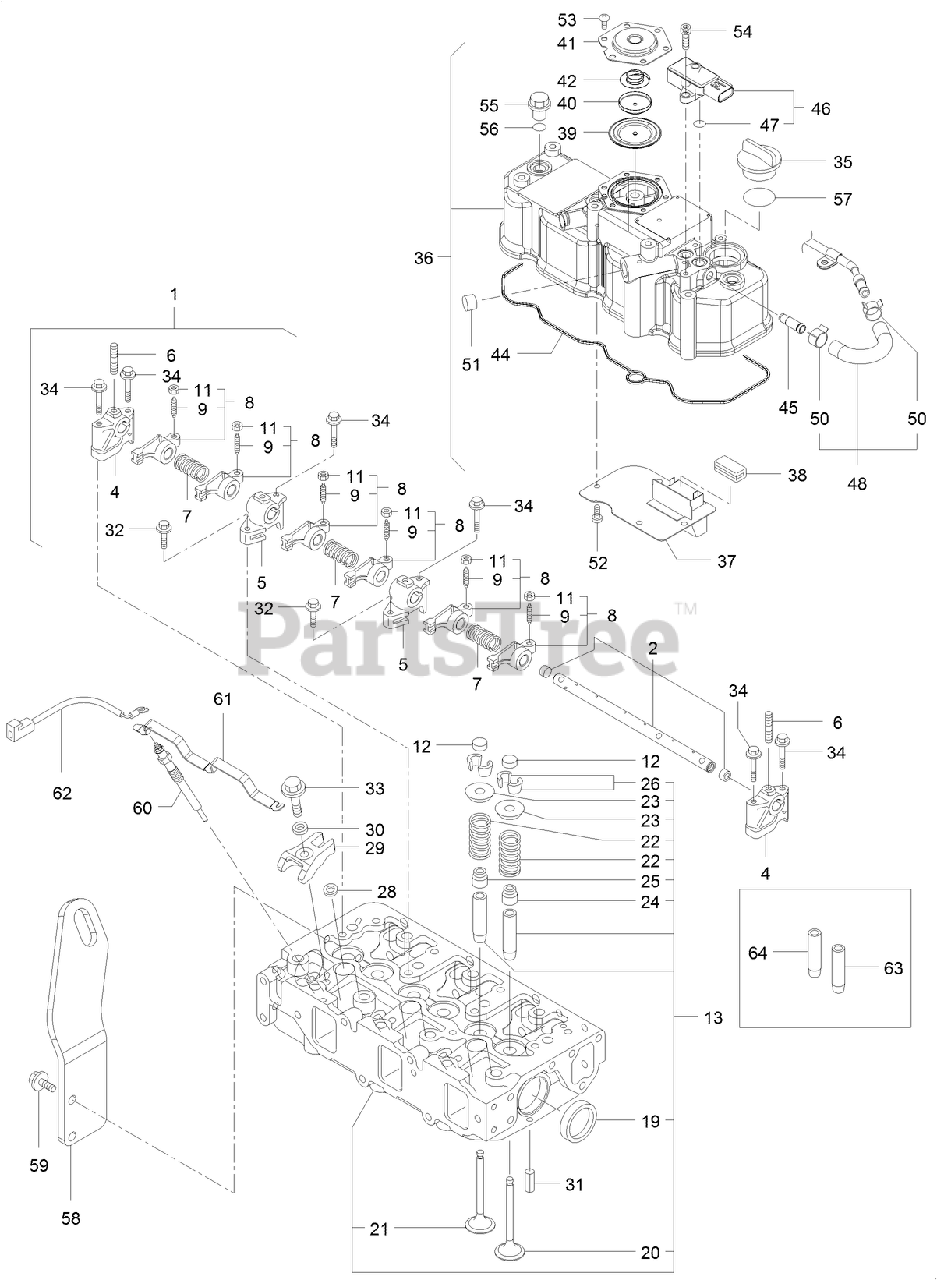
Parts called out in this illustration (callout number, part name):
1	SHAFT ASM
4	SUPPORT
5	SUPPORT
6	BOLT,STUD
7	SPRING
8	ARM-ROCKER
9	SCREW-ADJUST, VALVE
12	CAP-VALVE
13	CYLINDER HEAD ASM
22	SPRING
23	RETAINER-SPRING
24	SEAL-STEM, VALVE
25	SEAL-STEM, VALVE
26	PIN-COTTER
28	GASKET-INJECTOR
29	RETAINER-INJECTOR
30	WASHER-INJECTOR
31	PIN-SPRING
35	COVER-FILLER
36	CYLINDER HEAD COVER ASM
38	BAFFLE
39	DIAPHRAGM
41	PLATE-BREATHER
42	SPRING-DIAPHRAGM
44	GASKET-HEAD, CYLINDER
46	SENSOR-PRESSURE
47	O RING-SENSOR, PRESSURE
48	HOSE ASM
50	CLIP-HOSE
56	O-RING
57	O-RING
58	LIFTER-ENGINE
59	BOLT
60	PLUG-GLOW
61	CONNECTOR-PLUG, GLOW
62	HARNESS-WIRE
64	GUIDE-VALVE
